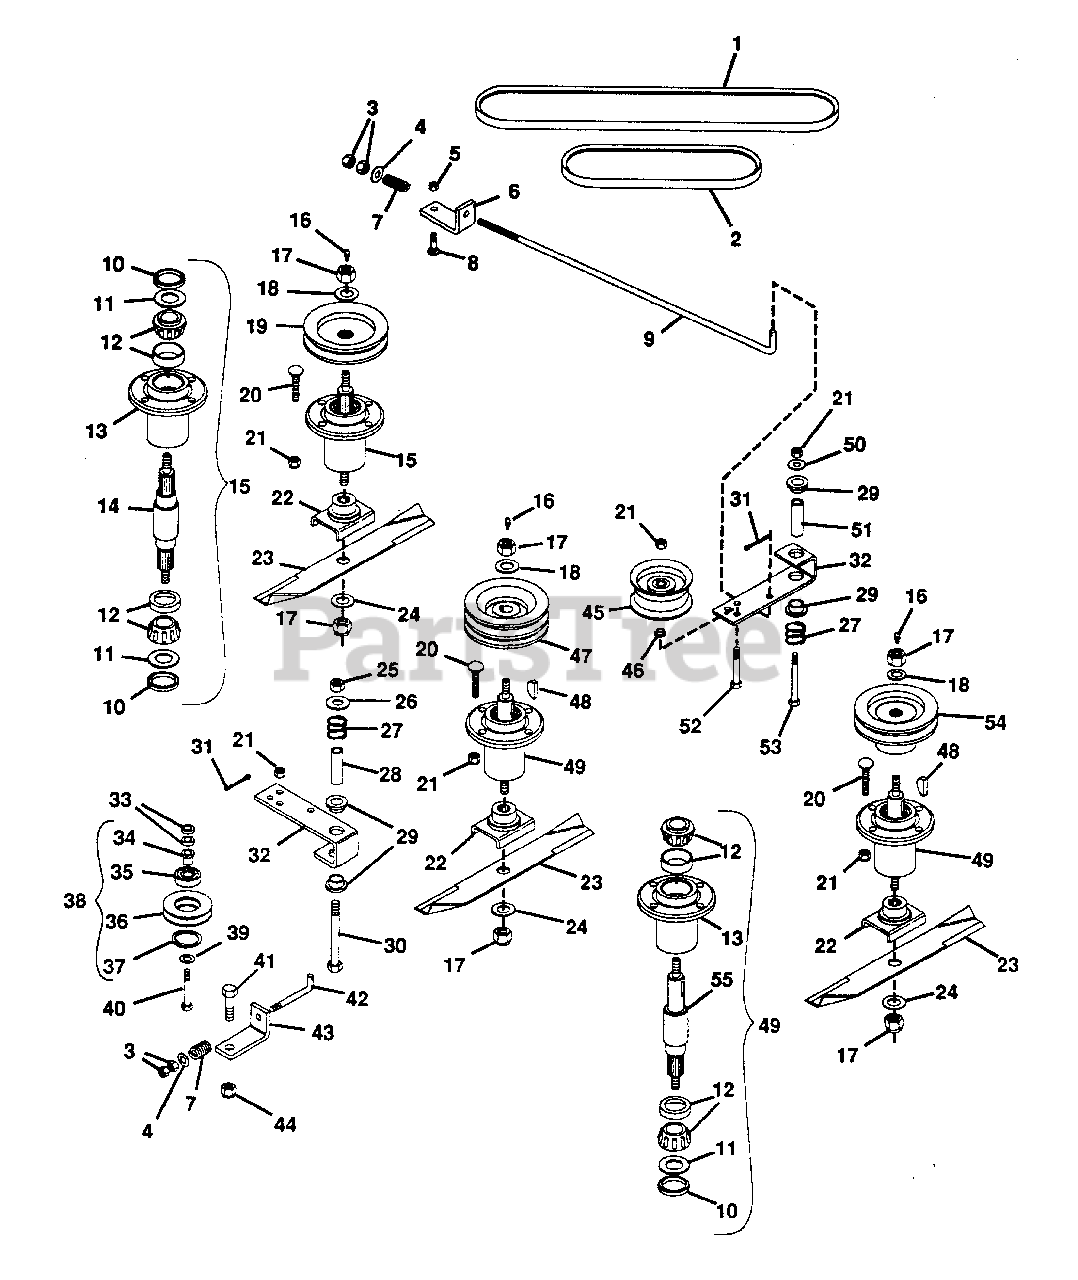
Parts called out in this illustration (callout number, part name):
1	BELT, 50" PM 18-H MOWER
2	BELT, MOWER A44
3	NUT, HEX 3/8-16
4	WASHER, FLAT .406X.812X.065
5	NUT, LOCK 5/16-18
6	BRACKET, BELT TENSIONER
7	SPRING, COMP. 1X.78
8	BOLT, CARRIAGE 5/16-18X1.00
9	ROD, IDLER
10	SEAL, STEEL(LEFT & CENTER SPINDLES)
10	SEAL, STEEL(RIGHT SPINDLE)
11	WASHER, FLAT .975X1.970X.030
11	(LEFT & CENTER SPINDLES)
11	WASHER, FLAT .975X1.970X.030(RIGHT SPINDLE)
12	ASSEMBLY, BEARING
13	HOUSING, BEARING
14	SHAFT, SPINDLE
15	ASSEMBLY, SPINDLE
16	FITTING, LUBE 1/8
17	NUT, LOCK 5/8-11
18	WASHER, FLAT .687X1.312X.122
19	SHEAVE, SPINDLE
20	BOLT 3/8-16X1.25 RD HD SQ NK
21	NUT, LOCK 3/8-16
22	WELDMENT, BLADE CRADLE
23	BLADE
24	WASHER, FLAT .656X1.312X.095
25	NUT, LOCK 1/2-13
26	WASHER, FLAT .531X1.250X.100
27	SPRING, COMP. 1X.80X36 LB/N
28	SPACER
29	BUSHING, NYLON .76X1X.6 FLG.
30	BOLT, HEX 1/2-13X3.50
31	PIN, COTTER .09X.75
32	ARM, IDLER PIVOT
33	SPACER, IDLER .406X.750X.188
34	BUSHING, IDLER SHEAVE
35	BEARING, BALL
36	SHEAVE, IDLER
37	RING, RETAINING
38	ASSEMBLY, IDLER SHEAVE
39	WASHER, FLAT .375X1.125X.065
40	BOLT, HEX 3/8-16X2.00
41	BOLT, HEX 1/2-13X1.25
42	ROD, IDLER
43	BRACKET, BELT TENSIONER
44	NUT, LOCK 1/2-13
45	PULLEY, IDLER
46	BUSHING
47	SHEAVE, SPINDLE
48	KEY, WOODRUFF .250X1 HARD
49	ASSEMBLY, SPINDLE
50	WASHER, FLAT .438X1.000X.083
51	SPACER
52	BOLT, HEX 3/8-16X2.25
53	BOLT, HEX 3/8-16X3.25
54	SHEAVE, SPINDLE
55	SHAFT, SPINDLE
